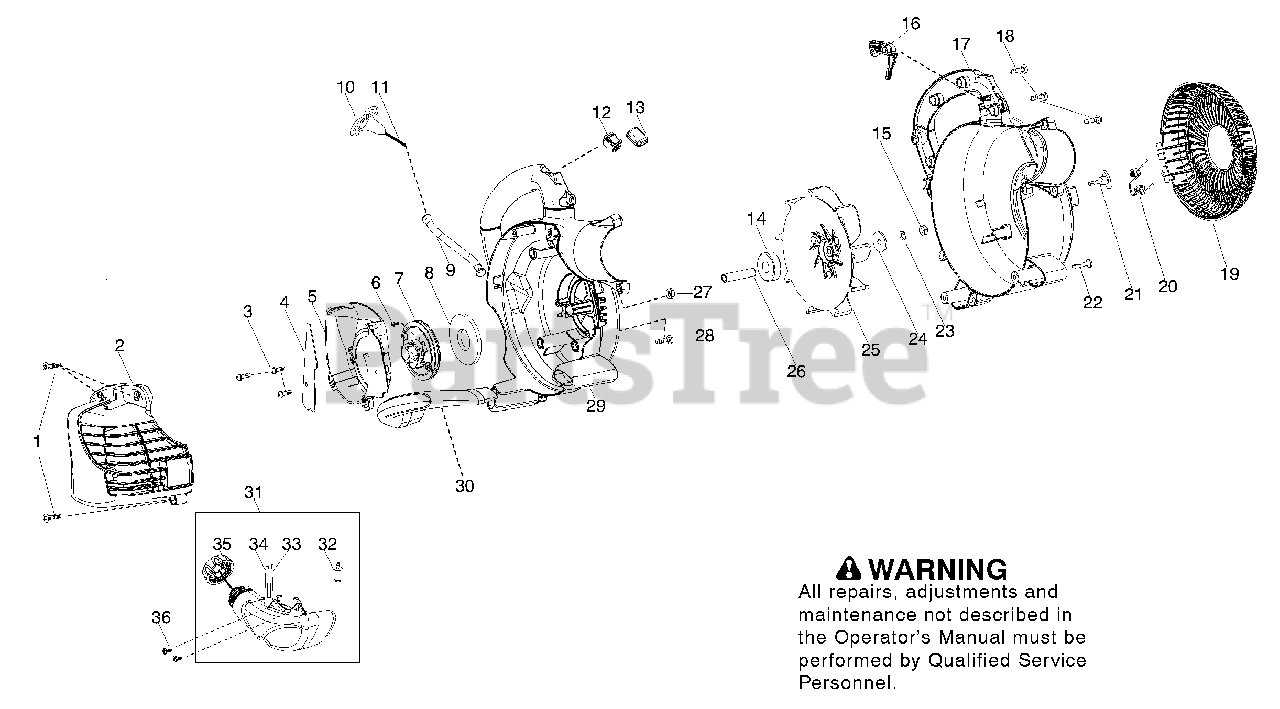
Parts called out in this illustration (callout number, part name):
2	Assy - Engine Cover
4	Shield - Baffle
7	Kit - Starter Pulley
8	Spring - Starter
9	Tube - Starter Rope
10	Handle - starter
12	Kit - Switch (momentary)
13	Protector - Switch
16	Trigger - Throttle
17	Assy - Scroll LH
20	Spring - Vac Door
21	Knob - Blower
22	Screw - Handle Vac
23	Washer - Lock
24	Washer - Impeller
25	Assy-Impeller
26	Spacer - Flywheel
28	Screw
29	Assy-Scroll Assy. RH
31	Assy - Fuel Tank
32	Assy - Fuel Pickup
33	Kit - Fuel Line (carb/purge)
34	Kit - Fuel Line (tank/purge)
35	Assy - Fuel Cap w/retainer
36	Screw - Fuel Tank Retainer
